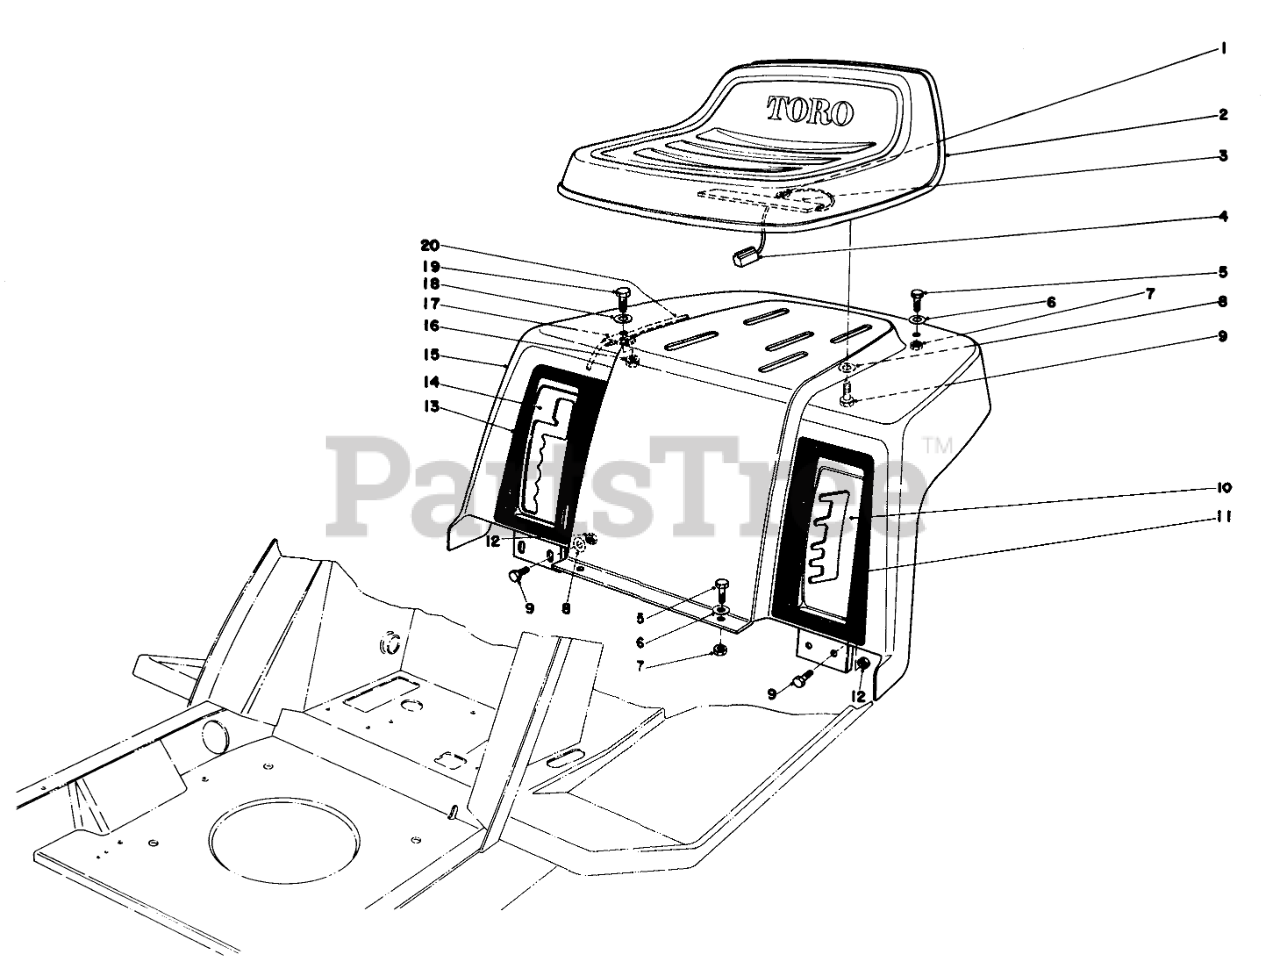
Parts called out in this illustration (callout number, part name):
1	Clip
2	Seat (Incl. Ref. #1, 3 & 4)
3	Seat Switch
4	Female-Connector
5	SCREW-HH
6	WASHER-FLAT
7	NUT-LOCK, CONE
8	WASHER-PLAIN
9	SCREW-HH
10	Quadrant Height of Cut
11	Decal Height of Cut
12	NUT-LOCK, CONE
13	Decal-Transmission
14	DETENT PLATE B
15	Rear Body
16	NUT-LOCK, SIDE
17	CABLE CLAMP
18	WASHER-FLAT
19	SCREW-HWH
20	Wire Harness
